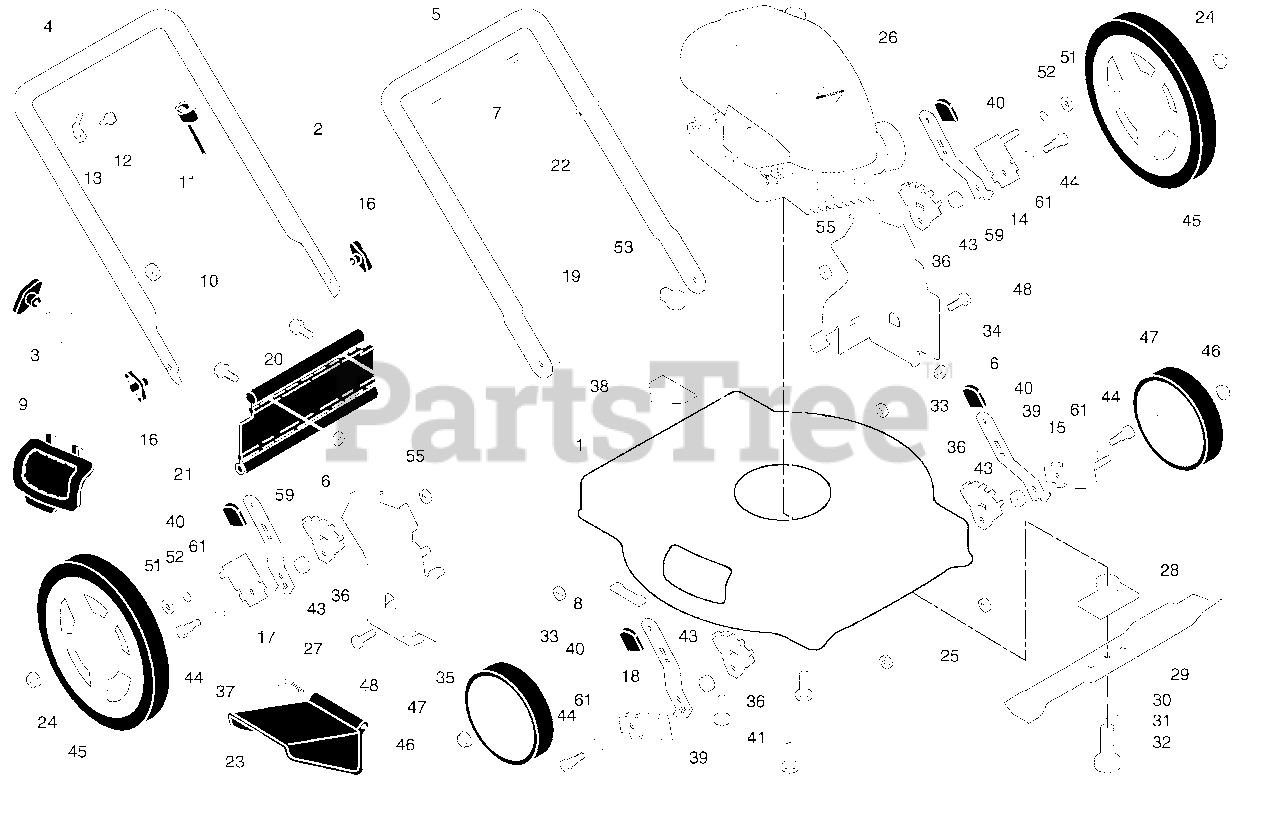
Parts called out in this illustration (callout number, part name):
1	Lawn Mower Housing
2	Control Bar
3	Rope Guide
4	Upper Handle
5	Lower Handle
6	Locknut, Hex 1/4-20
7	Handle Bolt 5/16-18
8	Clip, Closeout
9	Mulcher Plate
10	Nut, Hex 1/4-20
11	Engine Zone Control Cable
12	Hex Washer Head Screw #10-24 x 1/2
13	Up-Stop Bracket
14	Axle Arm Assembly, Rear, LH
15	Axle Arm Assembly, Front, LH
16	Handle Knob
17	Axle Arm Assembly, Rear, RH
18	Axle Arm Assembly, Front, RH
19	Hairpin Cotter
20	Screw, Hex Cap Head 1/4-20
21	Rear Deflector
22	Wire Tie
23	Discharge Guard
24	Nut, Hex, Flangelock 3/8-16
25	Nut, Hex, Flangelock 5/16-18
27	Torsion Spring
28	Blade Adapter
29	22" Blade
30	Hardened Washer
31	Helical Lockwasher 3/8
32	Screw, Hex Head, Grade 8, 3/8-24 x 1-3/8
33	Nut, Hex, Nylock 5/16-18
34	Wheel Bracket Support, LH
35	Wheel Bracket Support, RH
36	Wheel Bracket Adjuster
37	Hinge Rod
38	Danger Decal
39	Selector Spring, Front
40	Selector Knob
41	Screw, Hex Head, Threaded, Rolled 3/8-16 x 1
43	Spacer
44	Shoulder Bolt 5/16-18
45	Wheel & Tire Assembly, Rear, 12"
46	Nut, Hex, Flangelock 3/8-16
47	Wheel & Tire Assembly, Front, 7"
48	Bolt, Hex Head 5/16-18
51	Washer, Flat 3/8
52	O-Ring
53	Clip, Cable
55	Nut, Hex
59	Selector Spring, Rear
61	Washer, Curved, Cylindrical
61	Operator's Manual, English
61	Operator's Manual, French
61	Repair Parts Manual
